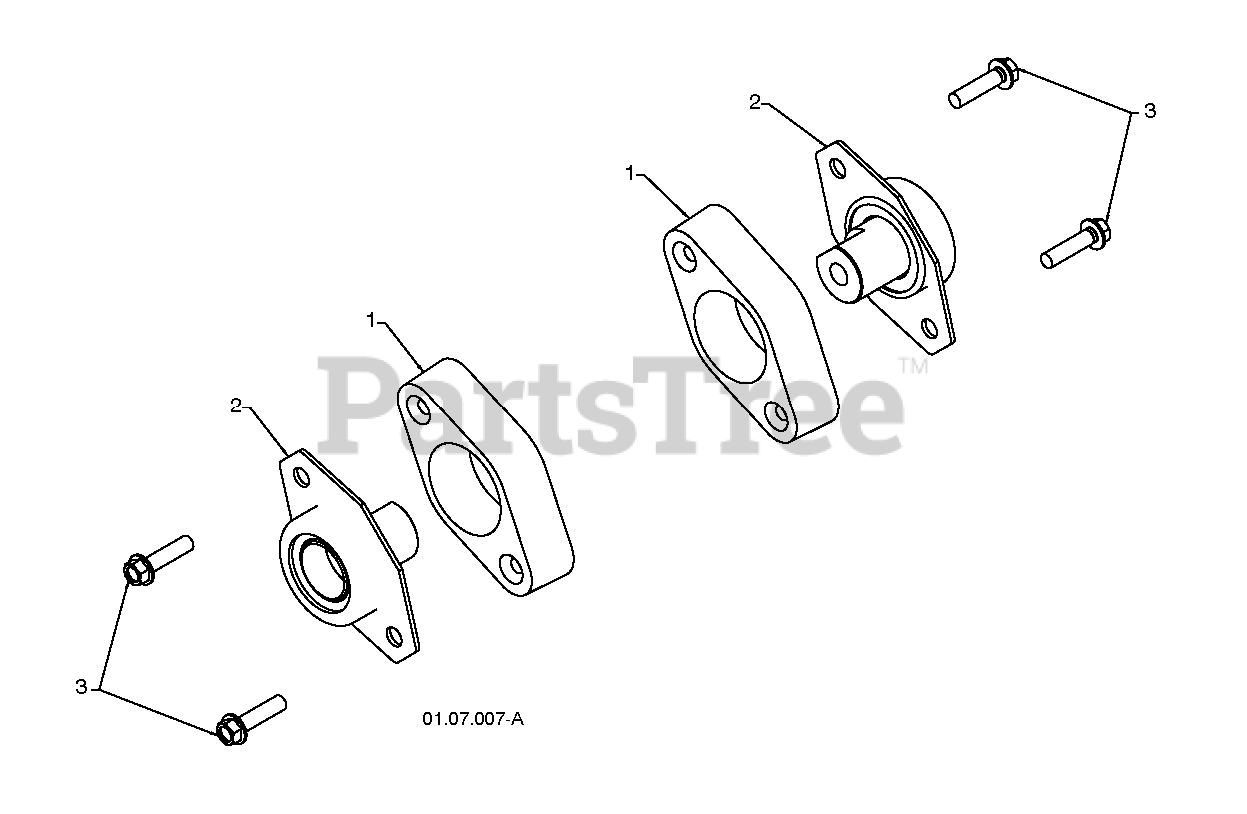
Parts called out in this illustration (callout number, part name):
1	BEARING RETAINER, PLASTIC
2	BEARING.BALL.AUGER
3	SCREW, HEX HD 5/16X1
